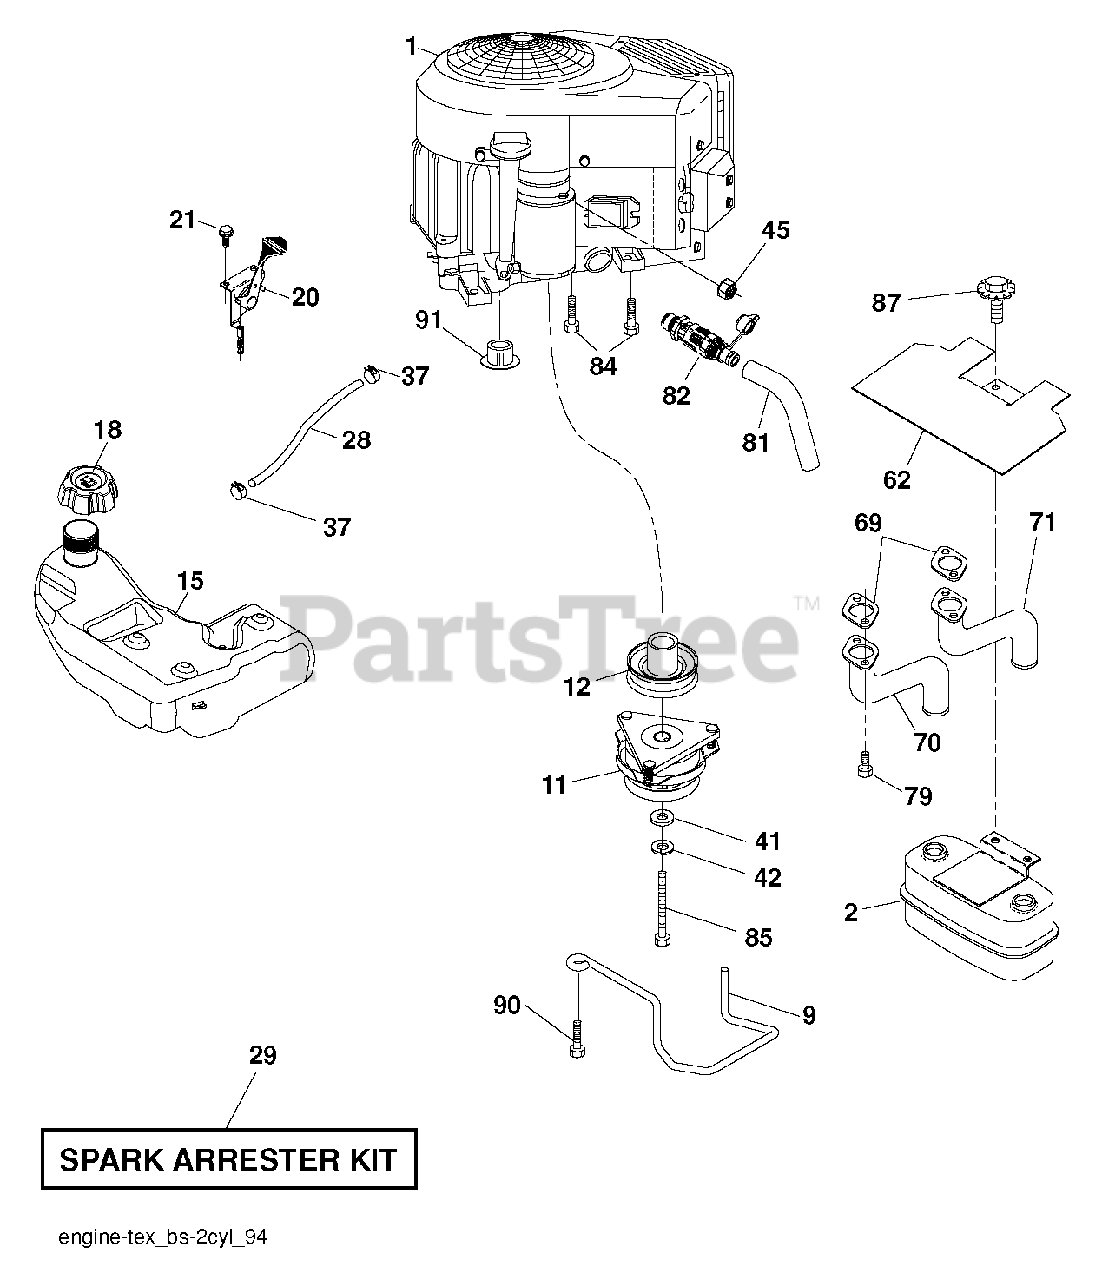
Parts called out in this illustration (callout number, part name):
2	MUFFLER.TWIN.CYL.LOW.TONE
9	KEEPER BELT ENGINE
11	CLUTCH ELECTRIC
12	PULLEY ENGINE
15	TANK.FUEL.4GAL
18	Fuel Tank Cap Assembly, 3" N-EPA Black
20	CONTROL.TH/CK.COBRA.B&S.TWN.
21	SCREW.#10 X 0.750.BOS (2 2)
28	LINE.FUEL.64"REAR.EMIS
29	KIT.SPARK ARRESTOR(392390 B&S)
37	HOSE CLAMP
42	LOCKWASHER
45	NUT
62	SHIELD.HEAT.MUFFLER
69	GASKET.MUFFLER
70	EXHAUST.TUBE.LH.BS/TWIN
71	EXHAUST.TUBE.RH.B&S.TWIN.INTEK
79	SCREW.SOCKET.HEAD.5/16-18
81	TUBE, DRAIN OIL ASM.
82	VALUE.OIL.DRAIN
84	SCREW.3/8-16
85	BOLT HEX 7/16-20 X 3.75 GR. 5
87	BOLT.5/16-18UNCX1.W/SEMS.BLK
90	SCREW 3/8-16X1
91	BUSHING.1.375OD
